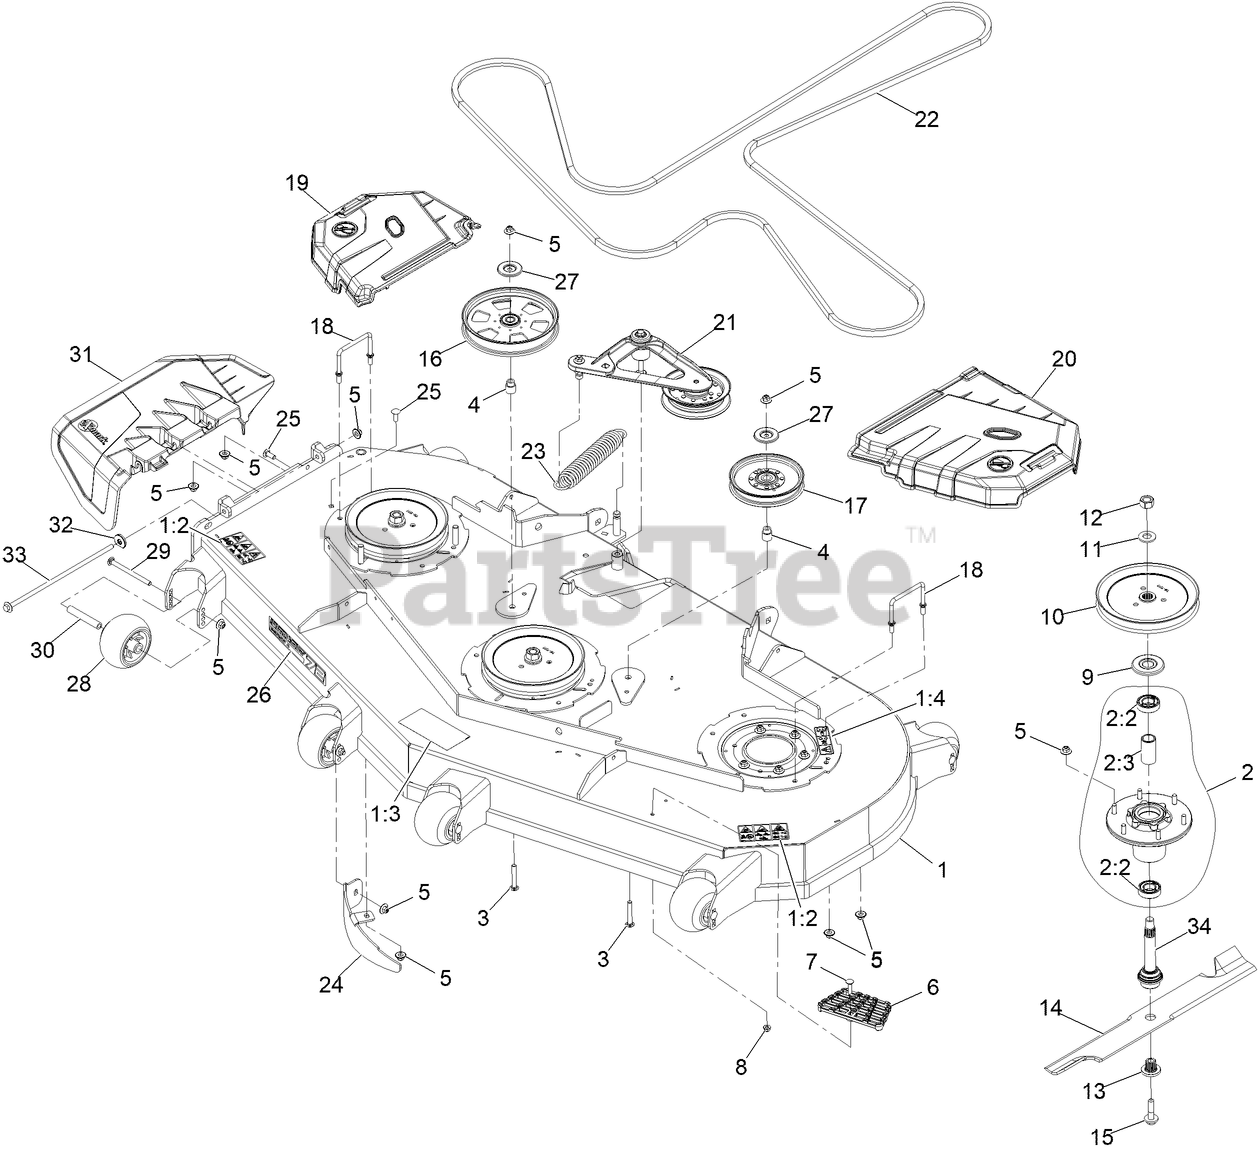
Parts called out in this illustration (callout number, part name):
1	ASM, Deck W/Decals 72
1:2	DECAL-ANTI-SCALP-BELT ROUTING
1:3	DECAL-COVER, MISSING
1:4	DECAL-DANGER THROWN OBJECTS
2	ASM-CUTTER HSG WITH BEARINGS
2:2	BEARING-BALL
2:3	SPACER-BEARING
3	SCREW-CARR
4	BUSHING-IDLER
5	Nut-Nyloc 3/8-16 Flg
6	STEP-DECK
7	Bolt-Carriage 5/16-18 X 1 1/4
8	NUT-HF, NI
9	GUARD,BEARING TOP .989
10	SHEAVE,BLADE DRIVE 8.74
12	NUT-HEX
13	BUSHING,SPLINED
15	SCREW,SEMS 1/2-20 X 2.19
16	PULLEY-IDLER, FLAT
17	IDLER-PULLEY
18	WIREFORM-COVER
19	SHIELD, RT
20	SHIELD, LT
21	DECK IDLER ASM
23	SPRING-EXTENSION
24	BAFFLE-DOGLEG, LZ72
25	SCREW-CARR
26	DECAL, 724
27	SHIELD-DUST
28	ROLLER-SCALP, ANTI
29	BOLT-CARR
30	SPACER-AXLE
31	Chute-Deck Discharge
32	Retainer, Chute
33	Pin, Chute
34	ASM-SPINDLE AND SEAL
